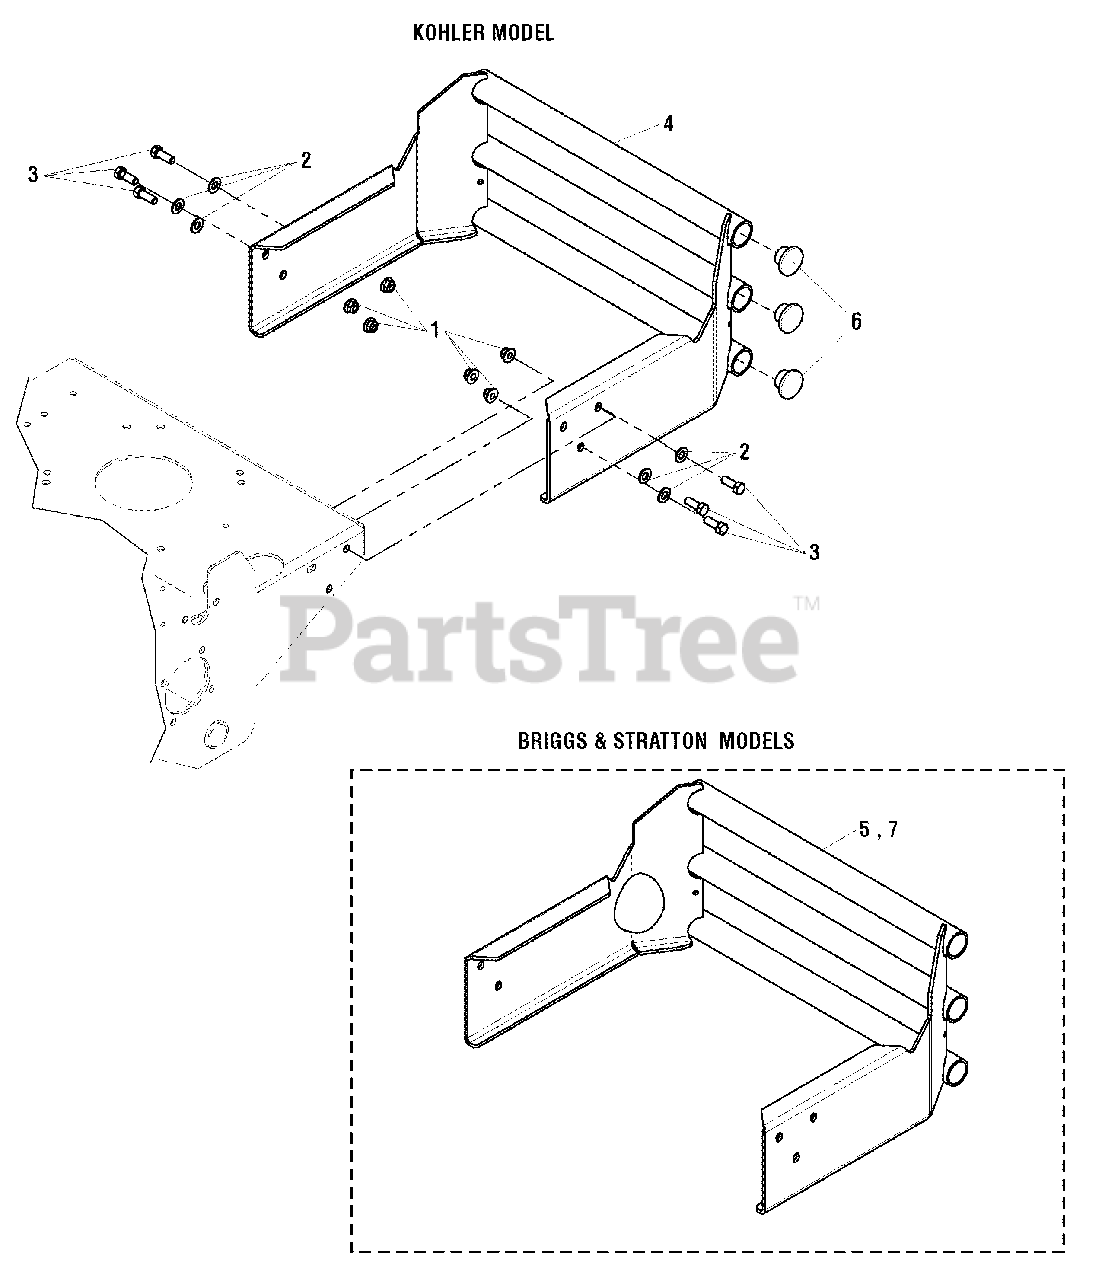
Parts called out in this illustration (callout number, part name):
1	NUT, 3/8-16 HEX NYLOCK FLANGE
2	WASHER, 3/8" GD.9 FLAT
3	BOLT, 3/8-16 X 1" GD5 YZ
4	WELD, BUMPER
5	WELD, BUMPER
6	PLUG, PANEL, 1.25 - BLACK
7	WELD, BUMPER
